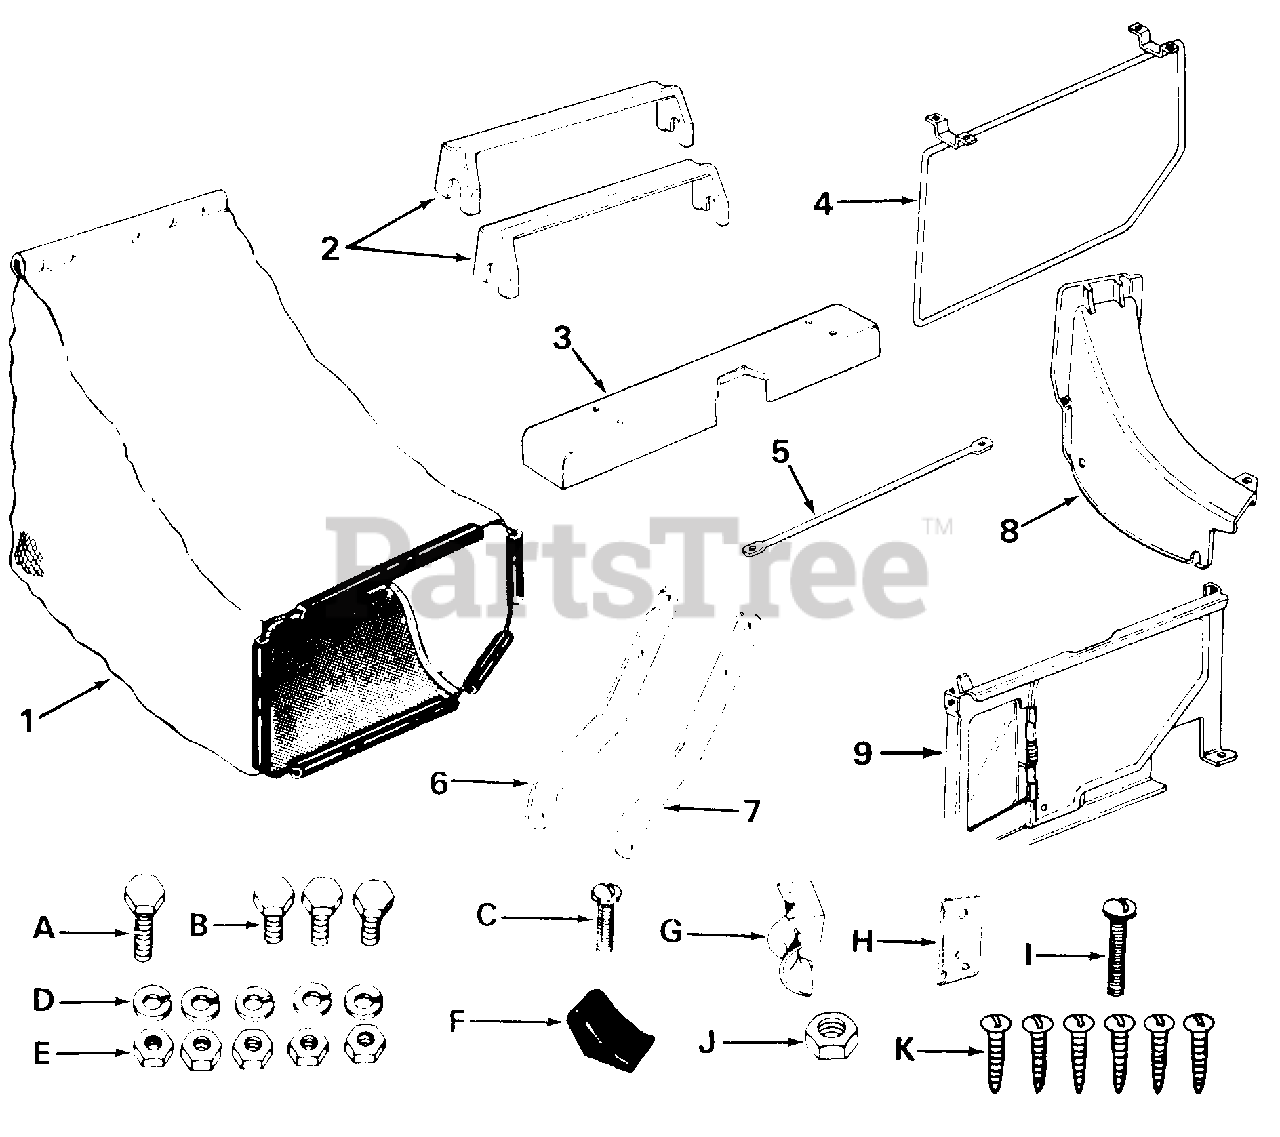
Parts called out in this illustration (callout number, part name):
1	Grass Bag
2	Grass Catcher Handle
3	Catcher Frame Cover
4	Front Catcher Frame
5	Bag Support
6	Panel Support Bracket
7	Panel Support Bracket
8	Top Discharge Chute
9	Top Catcher Panel
A	Hex Bolt 1/4-20 x 5/8" Lg.*
B	Hex Bolt 1/4-20 x 1/2" Lg.*
C	Truss Machine Screw 1/4-20x 1/2" Lg.*
D	Lock Washer 1/4" I.D.*
E	Hex Nut 1/4-20 Thread*
F	Door Grip
G	Rope Guide Half
H	Rope Retainer Clip
I	Truss Machine Screw 1/4-20 x 1.0" Lg.
J	Hex Nut 5/16-18 Thread*
K	Truss Machine Self-Tap Screw 1.0" Lg.
